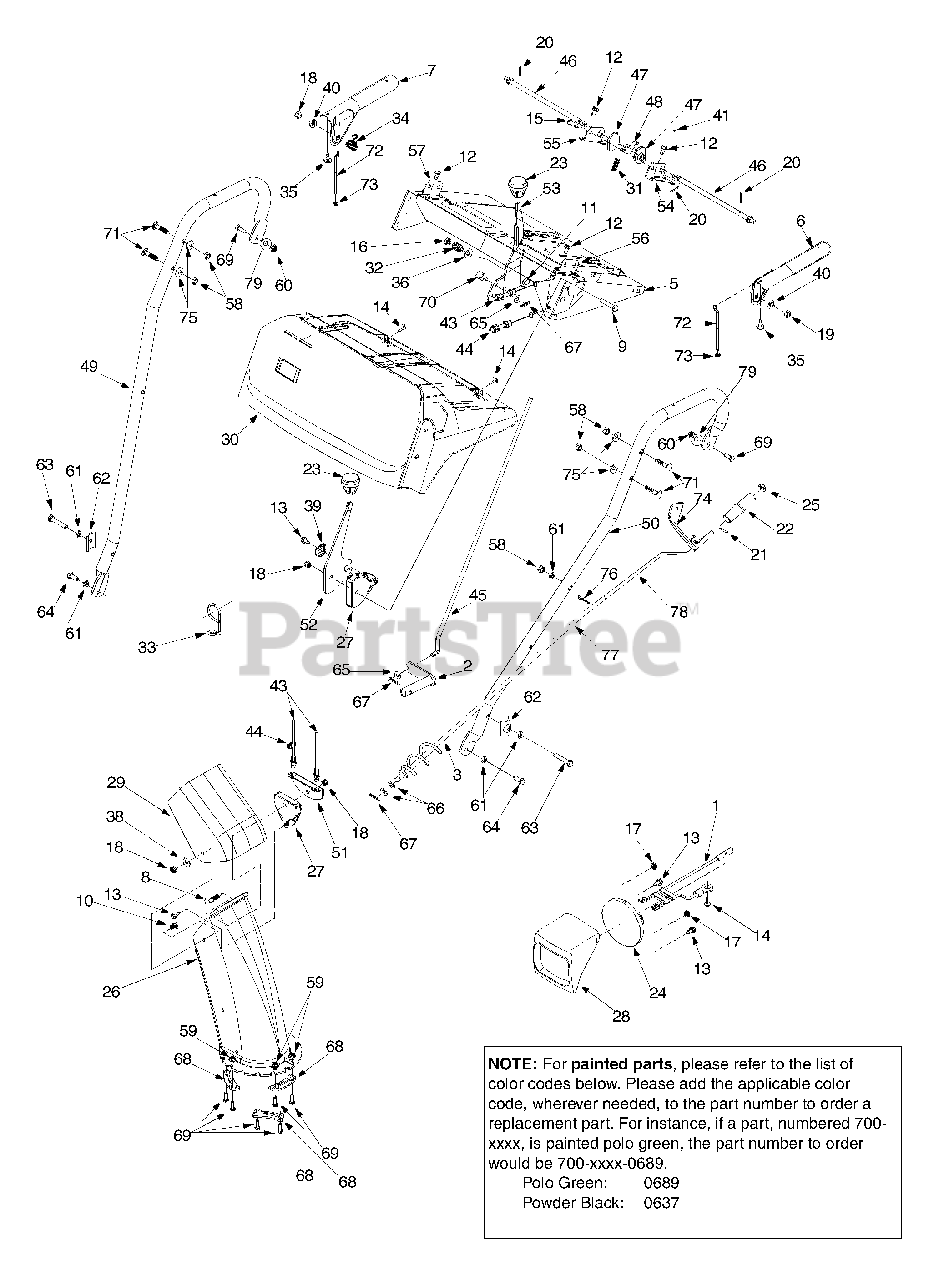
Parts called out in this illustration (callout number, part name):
1	Harness for Headlight
2	Shift Arm Assembly
6	Handle Assembly Engagement (L.H.)
7	Handle Assembly Engagement (R.H.)
8	Carriage Bolt 5/16-18 x 1.50
9	Hex Bolt 5/16-18 x 1.5
10	Carriage Bolt 5/16-18 x.75
11	Hex Screw 3/8-24 x 1.5
12	Hex Washer Hd. TT Screw 1/4-20 x 0.5"
13	Hex AB Tap Screw 1/4 x .62
14	Hex B-Tapp Screw # 10-16 x .62
15	Clevis Pin
16	Hex Ins. Lock Nut 3/8-24
17	Self-Threading Nut
18	Lock Nut 5/16-18
20	Cotter Pin
21	Roll Pin
22	Chute Crank Knob
23	Shift Knob
24	Headlight
25	Push Cap
26	Lower Chute
27	Cable Guide
28	Headlight Bezel
29	Upper Chute
30	Handle Panel
31	Compression Spring
32	Compression Spring
33	Cable Control Wire
34	Torsion Spring
35	Rubber Bumper
36	Bell Washer .380 x .880 x .062
38	Special Washer
39	Special Washer
40	Grease
43	Chute Deflector Control Cable
44	Chute Deflector Cable w/ Clip
45	Shift Rod
46	Cam Rod
47	Cam Handle Lock
48	Pawl Handle lock
58	Hex Nut 5/16-18 Thd.
59	Hex Flange Locked Nut 1/4-20 Thd.
60	Hex Nut 1/4-20
61	Lock Washer 5/16
62	Handle Tab
63	Hex Bolt 5/16-18 x 1.75 Gr.5
64	Hex Bolt
65	Flat Washer 5/16
66	Flat Washer 3/8 x .738 x .063
67	Hairpin Clip
68	Chute Flange Keeper
69	Hex Bolt 1/4-20 x 0.75" Gr.5
70	Ferrule
71	Carriage Bolt 5/16-18 x 1.50
72	Z Fitting
73	Hex Nut # 10-24
75	Cupped Washer
76	Hairpin Clip
77	Spacer
79	Bell Washer
